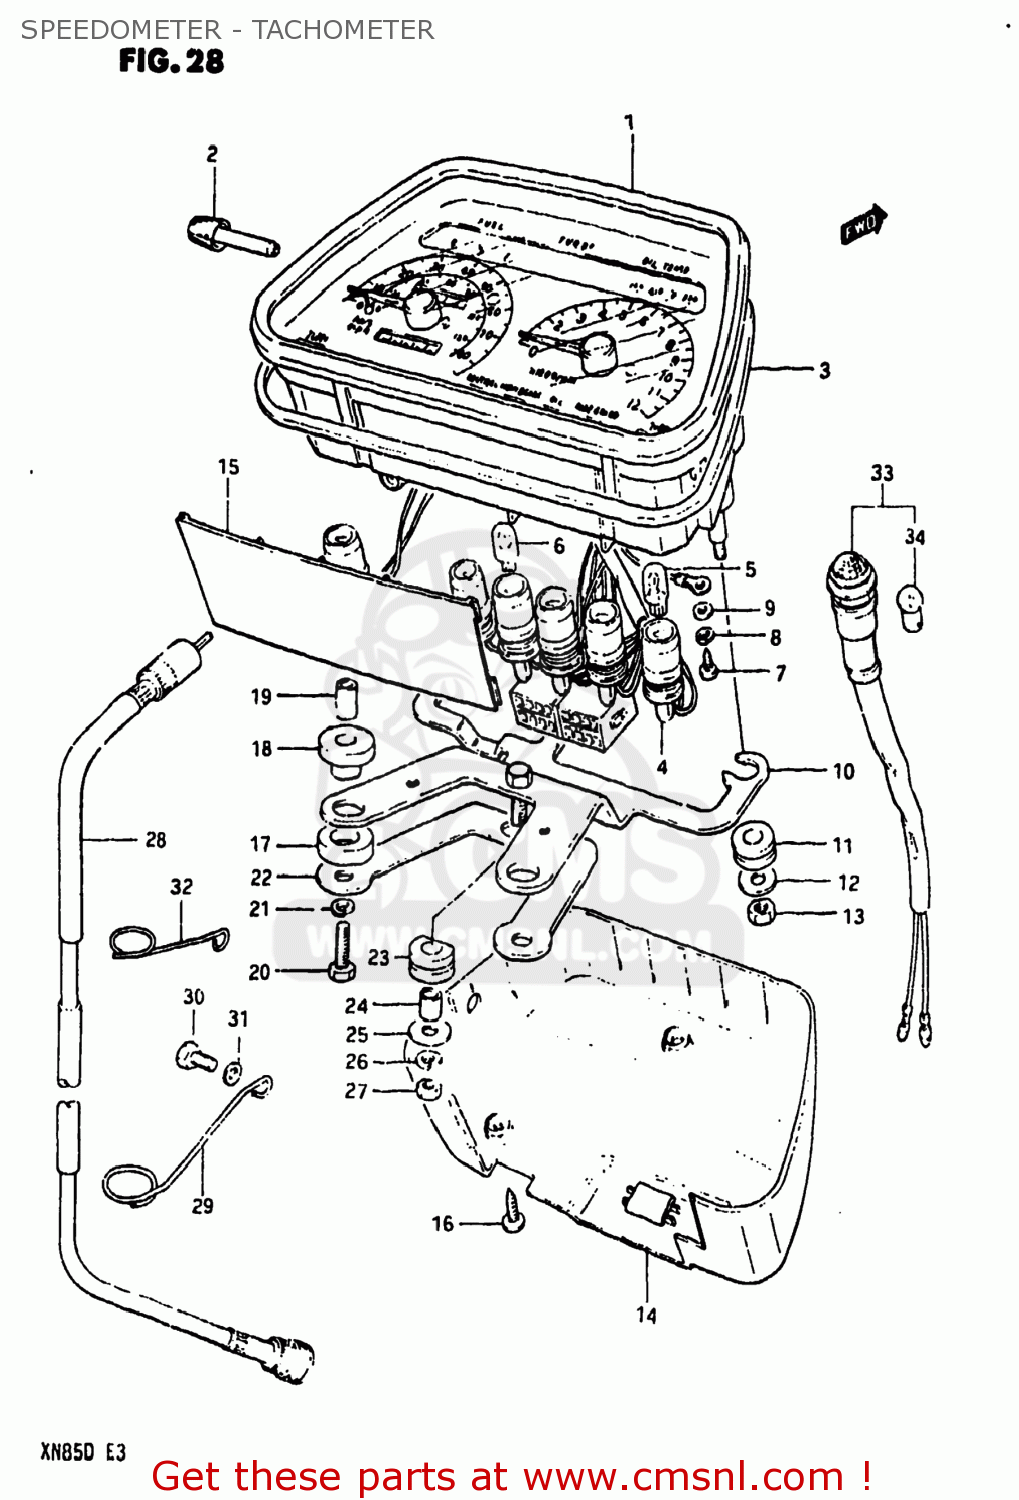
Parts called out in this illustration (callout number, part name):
1	METER,SPEEDOMETER/TACHOMETER (KM/
2	KNOB,TRIP METER
3	CUSHION,METER
4	SOCKET,METER
5	BULB(12V3.4W,T10)
6	BULB(12V1.7W,T10,WB121)
7	SCREW 3X12
8	LOCK WASHER
9	WASHER
10	BRACKET,METER
11	CUSHION,METER
12	WASHER,METER
13	NUT
14	COVER,METER,UNDER
15	PLATE
16	SCREW
17	CUSHION,METER BRACKET
18	CUSHION
19	SPACER(6.1X8X14.5)
20	BOLT
21	LOCK WASHER
22	BRACKET,METER
23	CUSHION,METER
24	SPACER (6.1X8X15.5)
25	WASHER(6.5X18X1.5)
26	LOCK WASHER
27	NUT
28	CABLE ASSEMBLY,SPEEDOMETER
29	CLAMP,SPEEDOMETER CABLE
30	BOLT, UPPER
31	WASHER
32	GUIDE,SPEEDOMETER CABLE UPR
33	LAMP ASSEMBLY,IDLE SWITCH
34	BULB(12V3.4W,STANLEY,A72A)
